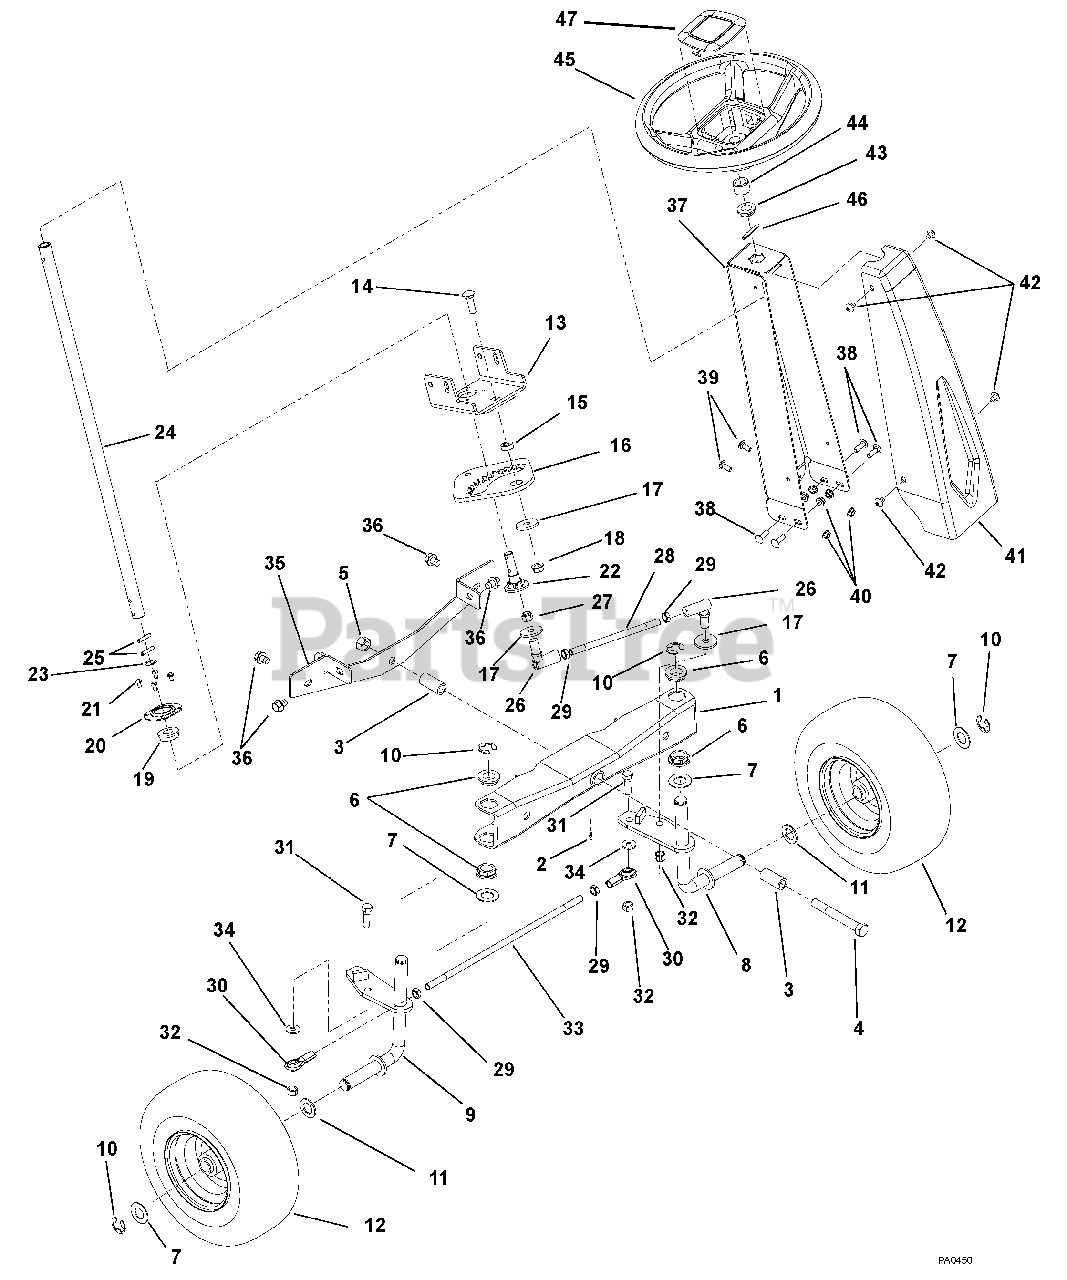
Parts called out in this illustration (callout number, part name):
1	WELDMENT, PIVOTING AXLE
2	FTG-LUBE .25-28X.256 YWZC
3	BSHG-SLV .500X.750X1.560
4	@BLT-HEX .50-13X4.00 GR5 YWZC
5	@NUT-LK-CTR .50-13 YWZC
6	FLANGE BUSHING
7	WSHR-HDND-THRST .755X1.40X.062
8	WMT, AMP SPINDLE, LH
9	WMT, AMP SPINDLE, RH
10	RG-RTNG-EXT .750X.050
11	WSHR-HDND-THRST .760X1.25X.094
12	TIRE/WHEEL 11X4 4P K500
13	SUPPORT, STEERING GEAR
14	@BLT-RDHDSQNK .38-16X1.25 G5YZ
15	STEER GEAR SPACER .38X.75X.269
16	GEAR, STEERING
17	WSHR-FL-STL .406X1.375X.135 YZ
18	@NUT-LK-TOP-FLG .38-16 YWZC
19	BSHG-FLG .625X1.156X.375 SI
20	RETAINING PLATE
21	SCR-TAP 10-24X.375 TORX PHD YZ
22	PINION- (8620)
23	WASHER, .500X.750X.020 THRUST
24	STEERING SHAFT
25	PIN,.188X1.0 HVY SPIRAL SPRING
26	BALL JOINT
27	NUT-LK-NYL .375-24 W/INSR YWZC
28	ROD. STEERING - AMP
29	NUT-JAM .375-24 YWZC
30	ROD END, .38 RH
31	@BLT-HEX .38-16X1.25 GR5 YWZC
32	@NUT-LK-CTR .38-16 YWZC
33	ROD, FRONT TIE - AMP
34	@WSHR-FL-STL.38X.875X.083 YWZC
35	SUPPORT,AXLE MOUNTING
36	@SCR-TAP .38-16X.50 HWH TR YWZ
37	BACK, STEERING COLUMN
38	@BLT-RHDSSQNK .31-18X1.00 G5YZ
39	@BLT-RHDSSQNK .31-18X.75 G5YZ
40	@NUT-LK-TOP-FLG .31-18 YWZC
41	COWL, STEERING COLUMN
42	SCR-TAP SERRDHDTX .31-18X.50BP
43	FLANGE BUSHING
44	SLEEVE, STEERING
45	STEERING WHEEL- AMP
46	PIN-ROLL .250X1.75
47	COVER, STEERING WHEEL
